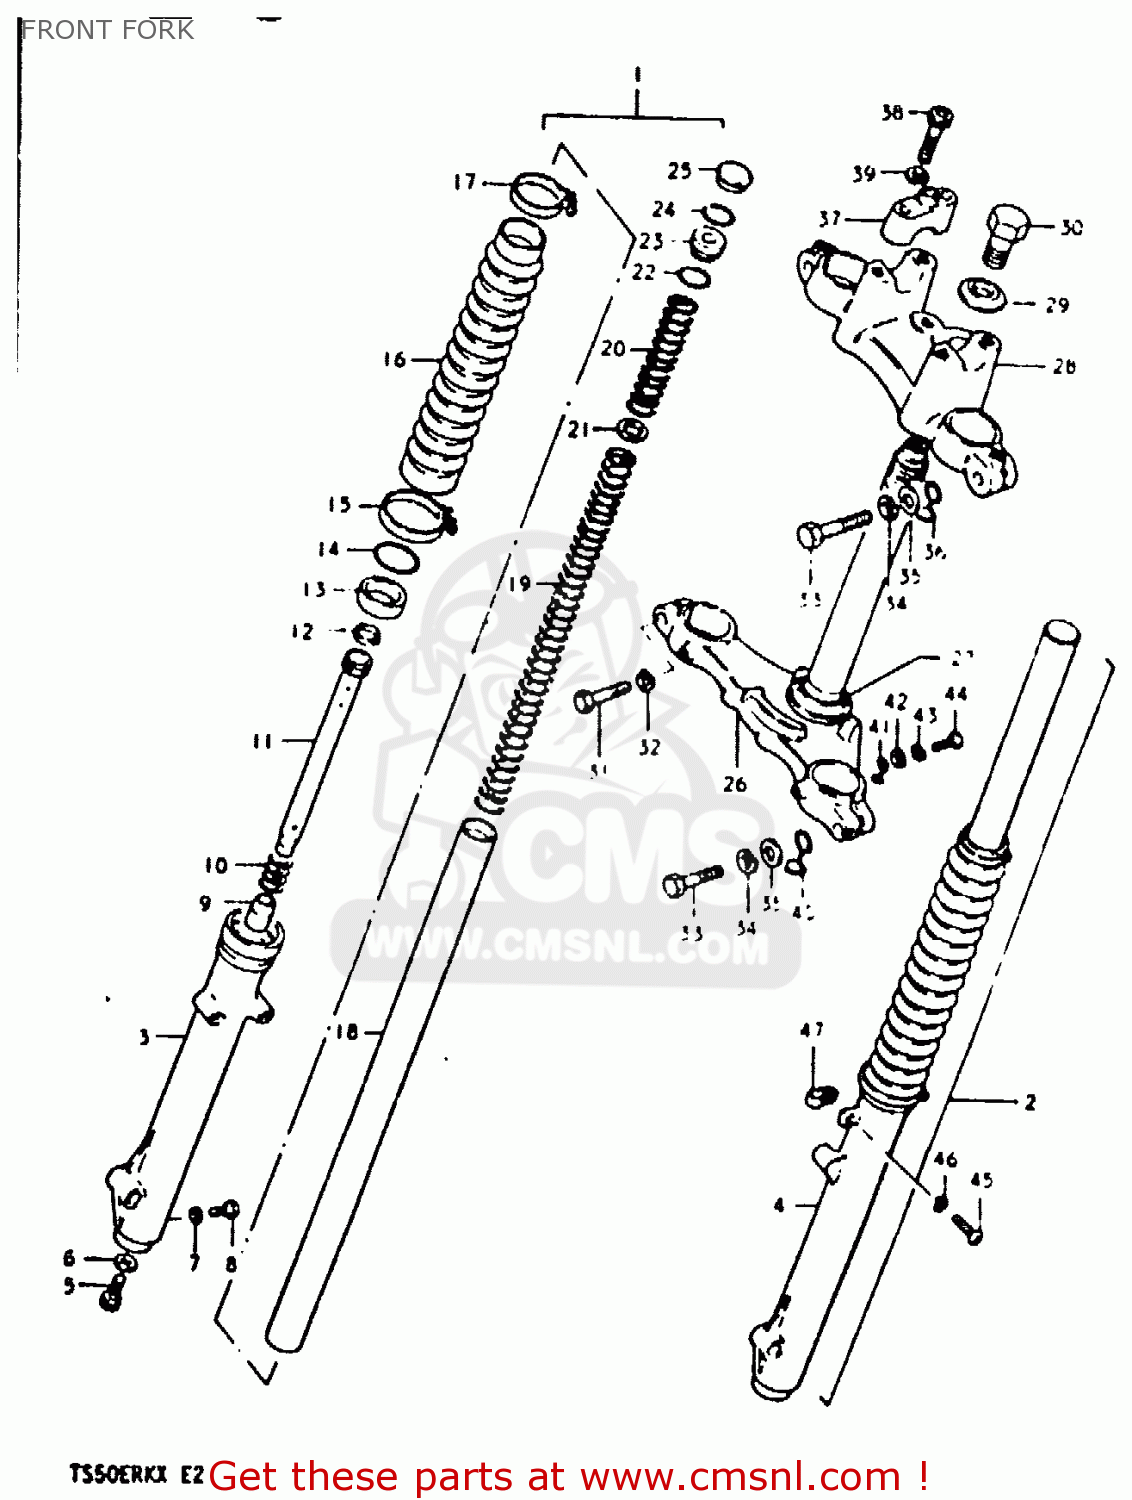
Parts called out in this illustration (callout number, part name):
1	DAMPER ASSY RH
2	DAMPER ASSY LH
3	OUTER TUBE RH
4	OUTER TUBE LH
5	BOLT(8X27)
6	GASKET (NAS)
7	GASKET,DRAIN,PLUG (NAS)
8	BOLT(6X8)
9	PIECE,OIL LOCK
10	SPRING,FORK REBOUND
11	CYLINDER,FRONT FORK
12	RING
13	OIL SEAL,FRONT FORK
14	CIRCLIP,FORK OIL SEAL
15	CLAMP
16	BOOT
17	BAND,FRONT FORK COVER BOOT
18	INNER TUBE
19	SPRING A
20	SPRING B
21	SEAT,SPRING
22	O RING
23	SEAT,SPRING
24	RING,STOPPER
25	CAP,FRONT FORK
26	STEM, STEERING
27	RACE,STEERING OUTER LWR
28	HEAD, STEERING STEM
29	WASHER(10.5X30X2.3)
30	BOLT
31	BOLT,M10X1.25X
32	LOCK WASHER
33	BOLT
34	LOCK WASHER
35	WASHER
36	CLIP
37	HOLDER,HANDLEBAR
38	BOLT 8X35
39	LOCK WASHER
40	CLIP
41	CLIP
42	WASHER
43	LOCK WASHER
44	SCREW 6X12
45	SCREW
46	LOCK WASHER
47	CLIP,FR BRAKE CABLE
